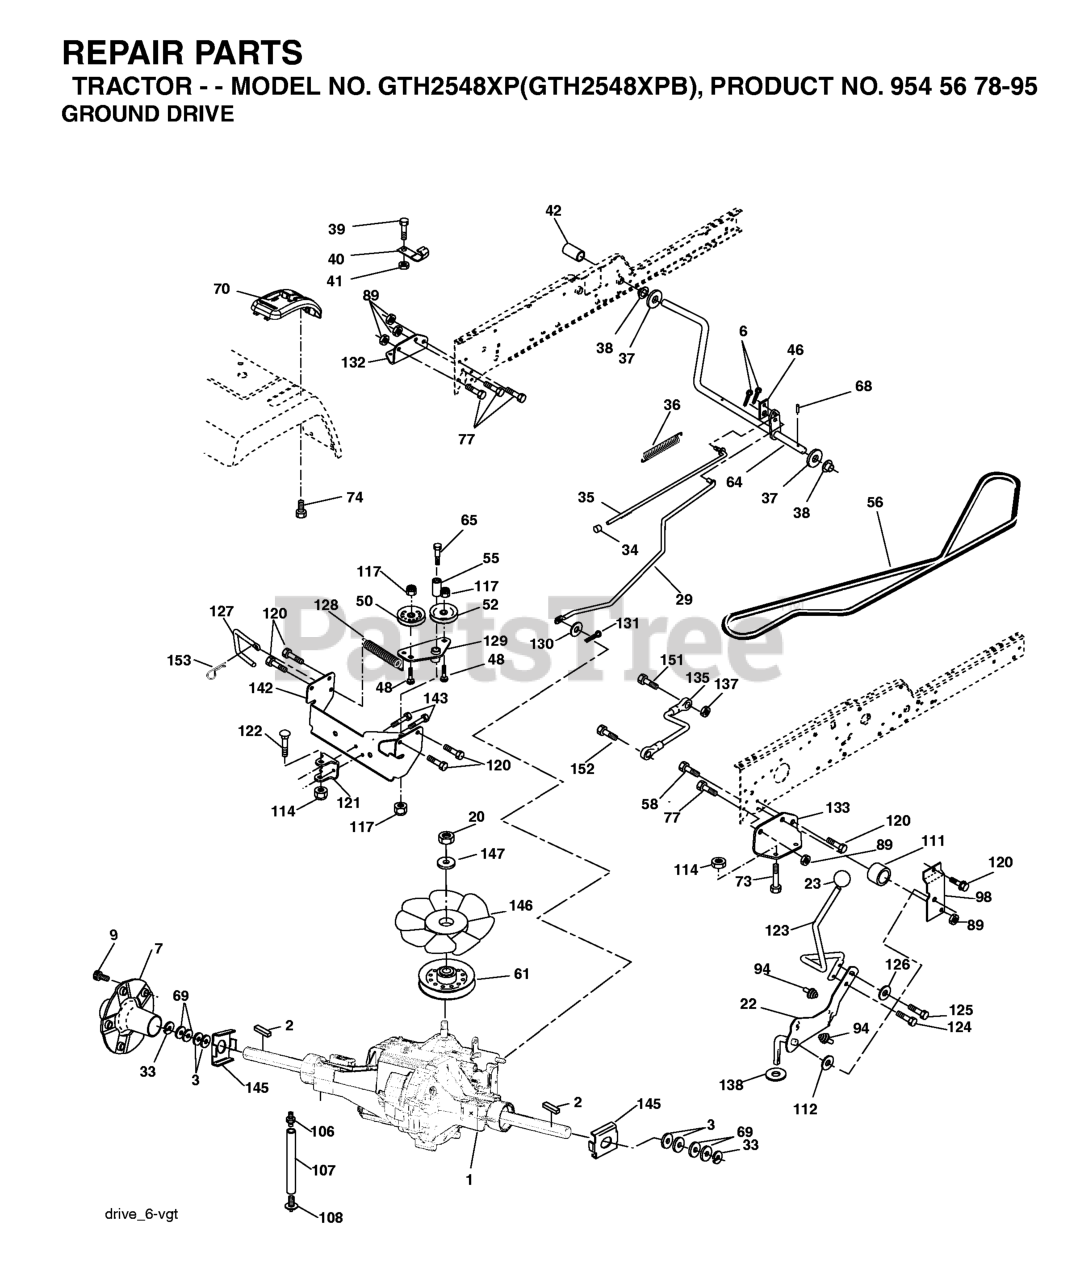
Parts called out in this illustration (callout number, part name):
2	KEY 1/4 X 2.5
6	COTTER PIN
7	HUB ASMBLY
20	NUT.HEX.1/2-20
22	LOWER SHIFT LEVER ASM
23	KNOB.DELUXE.(PISTOL.GRIP).BLAC
29	BRAKE, ROD
33	E RING HYT
34	PLUNGER CAP
35	PARKING BRAKE ROD
36	SPRING DRIVE GROUND
39	Screw, Fin. #10-24 x 1
40	ACTUATOR INTERLOCK SWITCH
41	Nut Centerlock 10-24 unc
46	RETAINER SPRING
50	FLAT IDLER PULLEY
52	IDLER PULLEY
55	BEARING LT (2 2)
56	BELT, V GROUND DRIVE
58	BOLT.HEX.7/16-14.FINISHED
61	PULLEY, TRANSAXLE
64	SHAFT.ASM.PEDAL.BRAKE
65	BOLT.SHLDR.3/8-16
68	ROLL PIN STD
70	CONSOLE AUTOMATIC YT.GT
73	BOLT HEX FLGHD 5/16-18X3 GR. 5
74	SCREW.HI-LO.CONSOLE
77	BOLT
89	Nut, Crownlock Hex 7/16-14 unc
94	FASTENER.XMAS.TREE
98	SHIFT BRACKET
106	O-RING KIT 70110
107	LINE.VENT.HYDRO-GEAR
108	CAP, VENT ASSY
111	SPACER SHIFT LEVER VGTH
112	WASHER NYLON HIGH TEMP
114	NUT.71038.31-18.HEX.NYLOCK
117	NUT LOCK FLG 3/8-16 UNC
120	SCREW 3/8-16X3/4
121	BRACKET STRAP TORQUE
122	BOLT.5/16-18X2.5
124	BOLT.SHOULDER.5/16-18X
126	WASHER.SRRTD.5/16
127	LINK CONTROL CLUTCH
128	SPRING DRIVE GRND
129	BRACKET ARM IDLER TENSIONING
131	COTTER PIN
132	BRACKET MTG HYDRO 3500 LH VGT
133	BRACKET MTG HYDRO 3500 RH VGT
135	LINK ASM CONTROL HYDRO 3500
138	THRUST WASHER
142	STRAP TORQUE HT-3500
143	SCREW 5/16"
145	WASHER.AXLE.FLANGE.HG-3000
146	FAN 7" HYDRO
148	SCREW.3/8-16
151	BOLT
152	BOLT HEX 5/16X1 W/PATCH
153	RETAINER M
